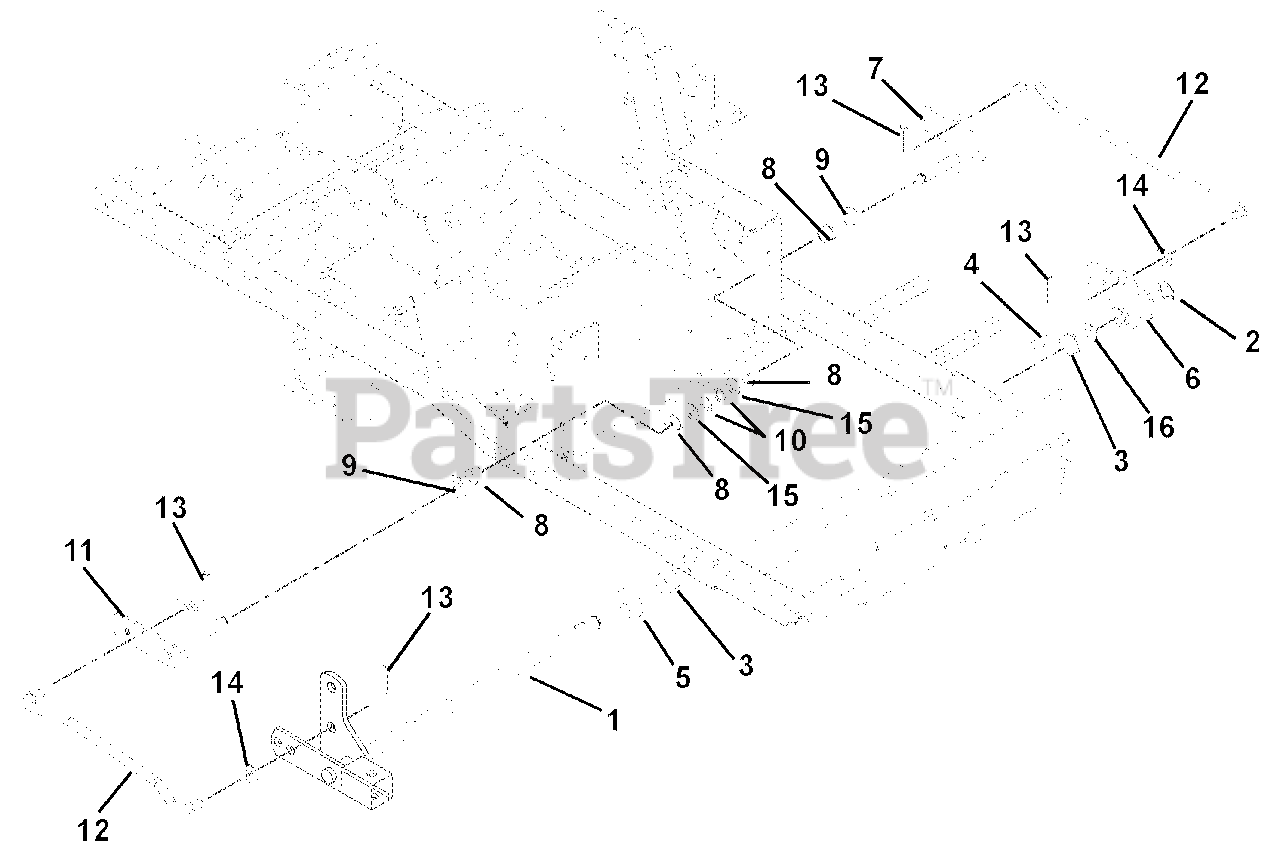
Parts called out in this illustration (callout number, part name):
1	Lift, Mower
2	Ring, Retaining External 1.00 x .078
3	Bushing, Flange Nylon 1.02 x 1.385 x .75 x 1.75
4	Key, Woodruff .25 x 1.00
5	Washer, Flat Steel 1.063 x 2.00 x .134
6	Weldment, Lift Arm-Front
7	Weldment, Rear Lift Arm-Left Hand
8	Bushing, Flange Nylon .762 x 1.0 x .58 x 1.48
9	Washer, Hardened Steel .758 x 1.23 x .031
10	Ring-Retaining-External .689 x .077
11	Weldment, Rear Lift Arm- Right Hand
12	Rod, Lift Assist 19.35"
13	Pin, Roll .25 x 1.25 Stainless Steel
14	Washer, Flat Steel .630 x 1.25 x .062
15	Washer, Flat Steel .755 x 1.25 x .125
16	Washer, Hardened Thrust 1.00 x 1.55 x .03
